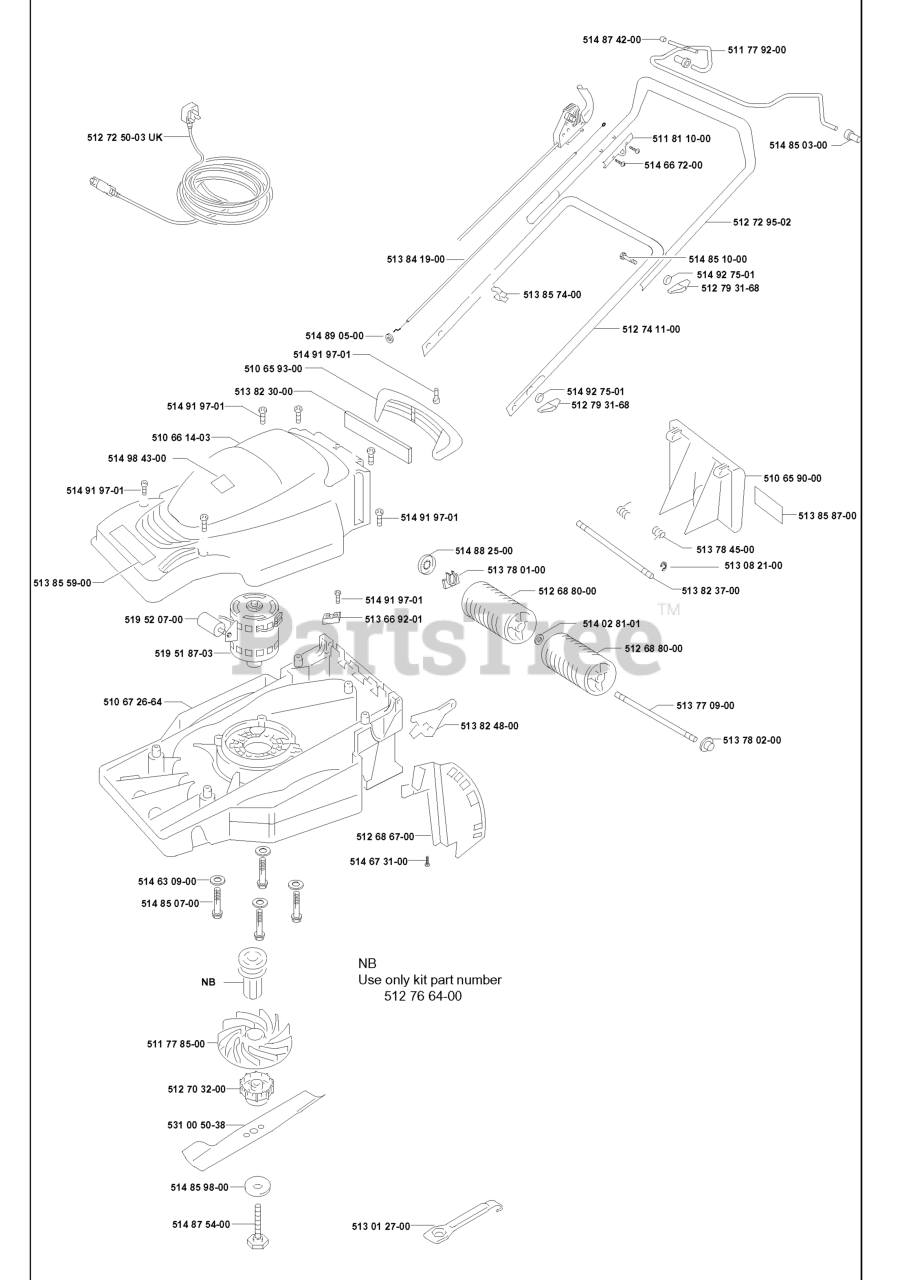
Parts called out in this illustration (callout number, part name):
3	CLEVIS PIN
11	Cotter Pins
14	NUT FLANGE
15	BOLT
31	NUT HEXAGON THIN ISO 4035 M12
